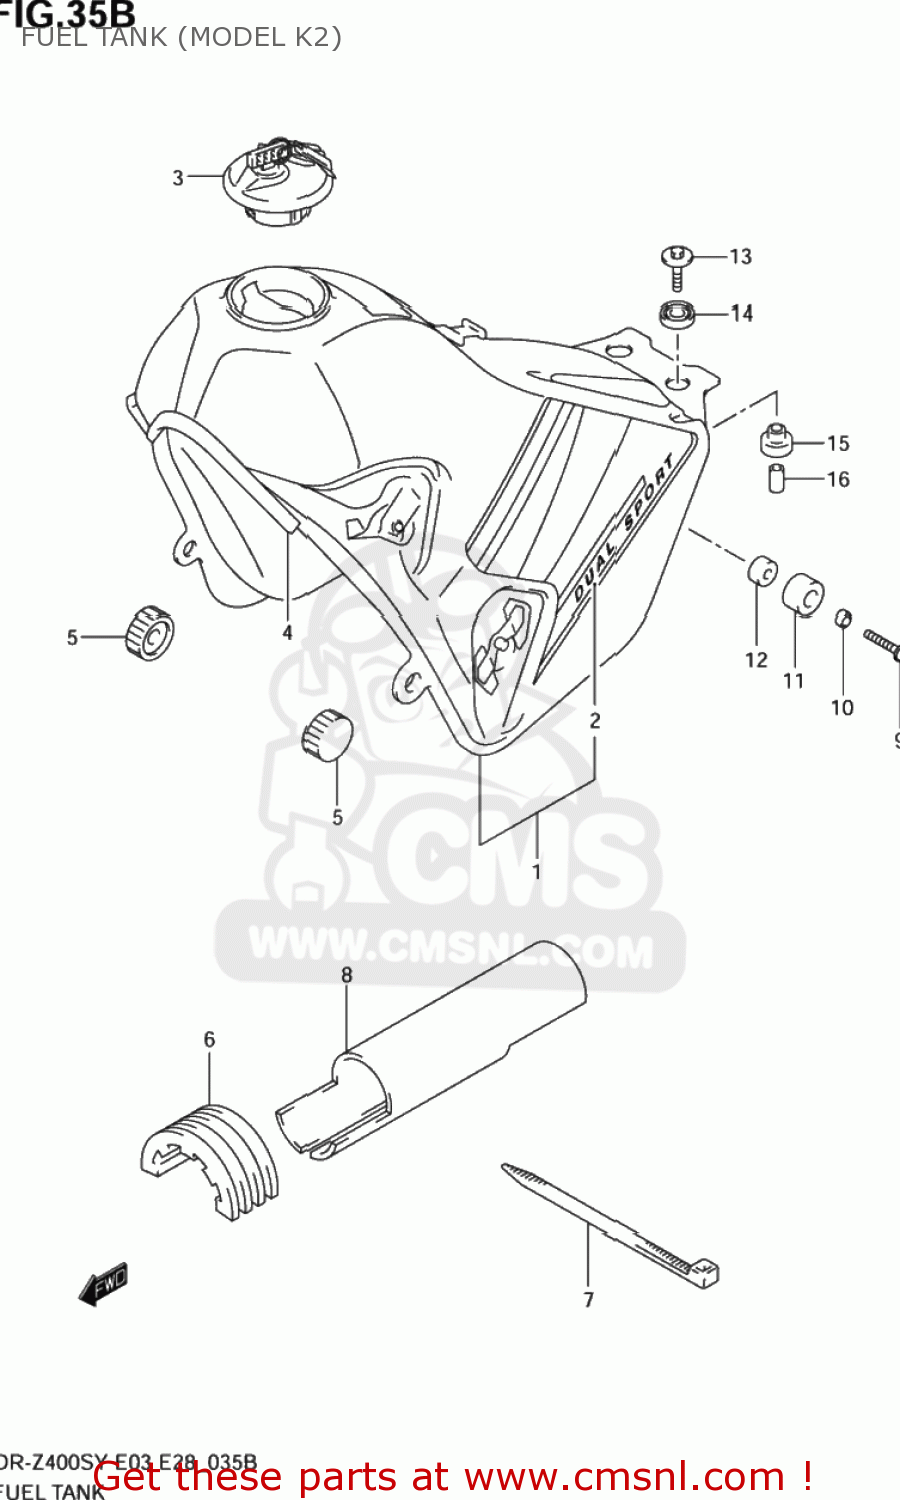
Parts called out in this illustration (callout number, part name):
1	TANK ASSY,FUEL(YELLOW)
2	TAPE SET,FUEL TANK
3	CAP SET,FUEL TANK
4	MOLDING
5	CUSHION
6	CUSHION,FUEL TANK
7	CLAMP(L:300)
8	SHIELD,FUEL TANK
9	SCREW
10	SPACER(6.5X20X9)
11	CUSHION
12	SPACER(6.5X9X5)
13	BOLT(6X30)
14	CUSHION
15	CUSHION
16	SPACER(6.5X9X18)
